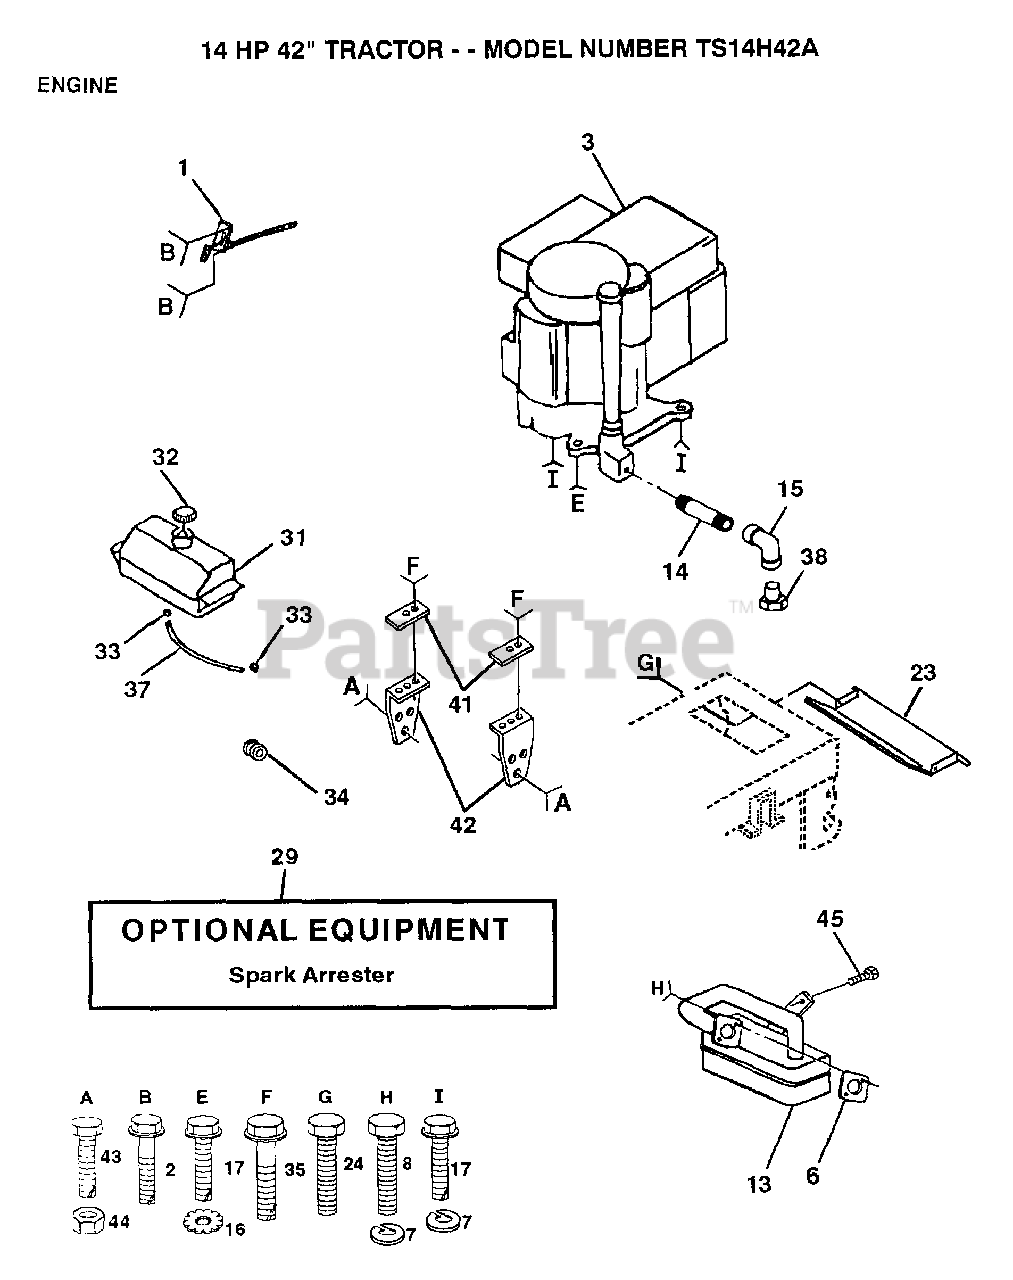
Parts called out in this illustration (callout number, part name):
1	THROTTLE CONTROL
2	SCREW LT
3	ENGINE KOHLER 14HP
7	LOCKWASHER
8	BOLT
13	MUFFLER.LT.12.5
14	PIPE NIPPLE
15	ELBOW
16	LOCKWASHER.5/16.E
23	HEAT SHIELD
24	SCREW
31	TANK.FUEL.LT.
33	HOSE CLAMP
35	SCREW
41	"CLAMP,FUEL TANK T"
42	BRKT FUEL TANK T
43	BOLT
